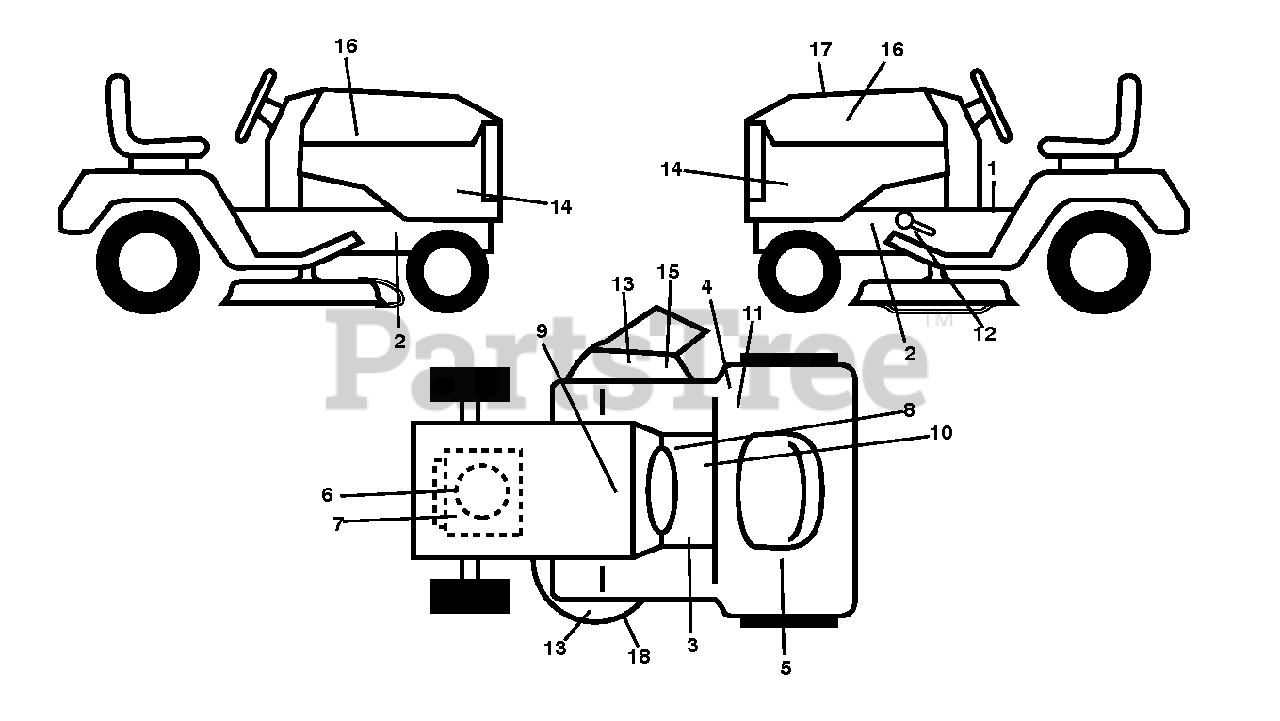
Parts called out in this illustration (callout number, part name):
1	LABEL
3	DECAL
4	DECAL 80 DBA
5	DECAL.WARN.RESERVE.FUEL
7	DECAL
8	DECAL PARK BRAKE
9	DECAL BTRY SYMBOLS
10	DECAL
11	DECAL
12	DECAL.PEDAL.HUSQ.CROWN
13	DECAL, NO STEP
15	DECAL, CAUTION
16	RP.DECAL.BADGE.170MM.TEXTLOGO
18	DECAL.MOWER.SCH.48/54
